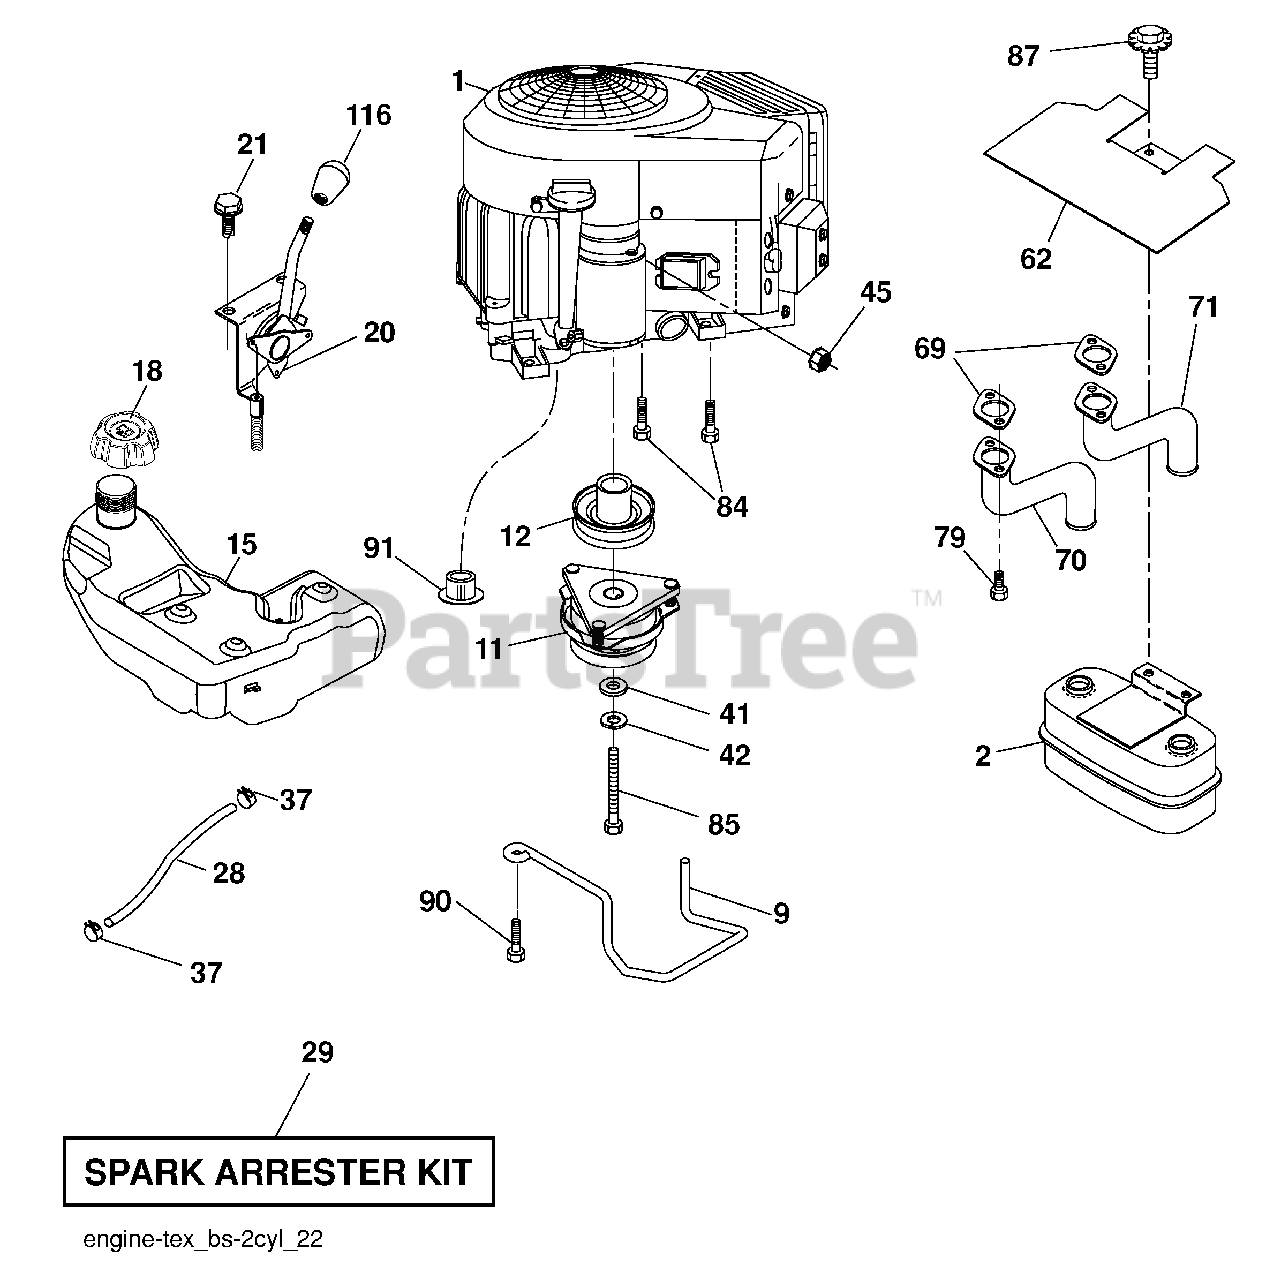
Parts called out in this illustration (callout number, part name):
9	Keeper Belt Engine
11	Clutch Electric
12	Pulley Engine
15	Tank Fuel
18	Cap
20	Control Throttle
21	Screw #10 x .750 BOS Thread
28	Fuel Line
29	Spark Arrester Kit
37	Clamp Hose
41	Washer 1-1/2 OD x 15/32 ID x .250
42	Washer Lock 7/16
45	Nut Keps Hex 1/4-20 unc
62	Heat Shield
70	Tube Exhaust
71	Exhaust Tube
79	Screw Socket HP 5/16-18 x 1
84	Screw 3/8-16 x 1-1/4
85	Bolt Hex 7/16-20 x 4 x Gr. 5-1.5 Thr
87	Bolt 5/16-18 unc x 3/4 w/Sems
90	Screw 3/8-16 x 1
91	Bushing 1.375 OD
116	Knob Soft Touch
